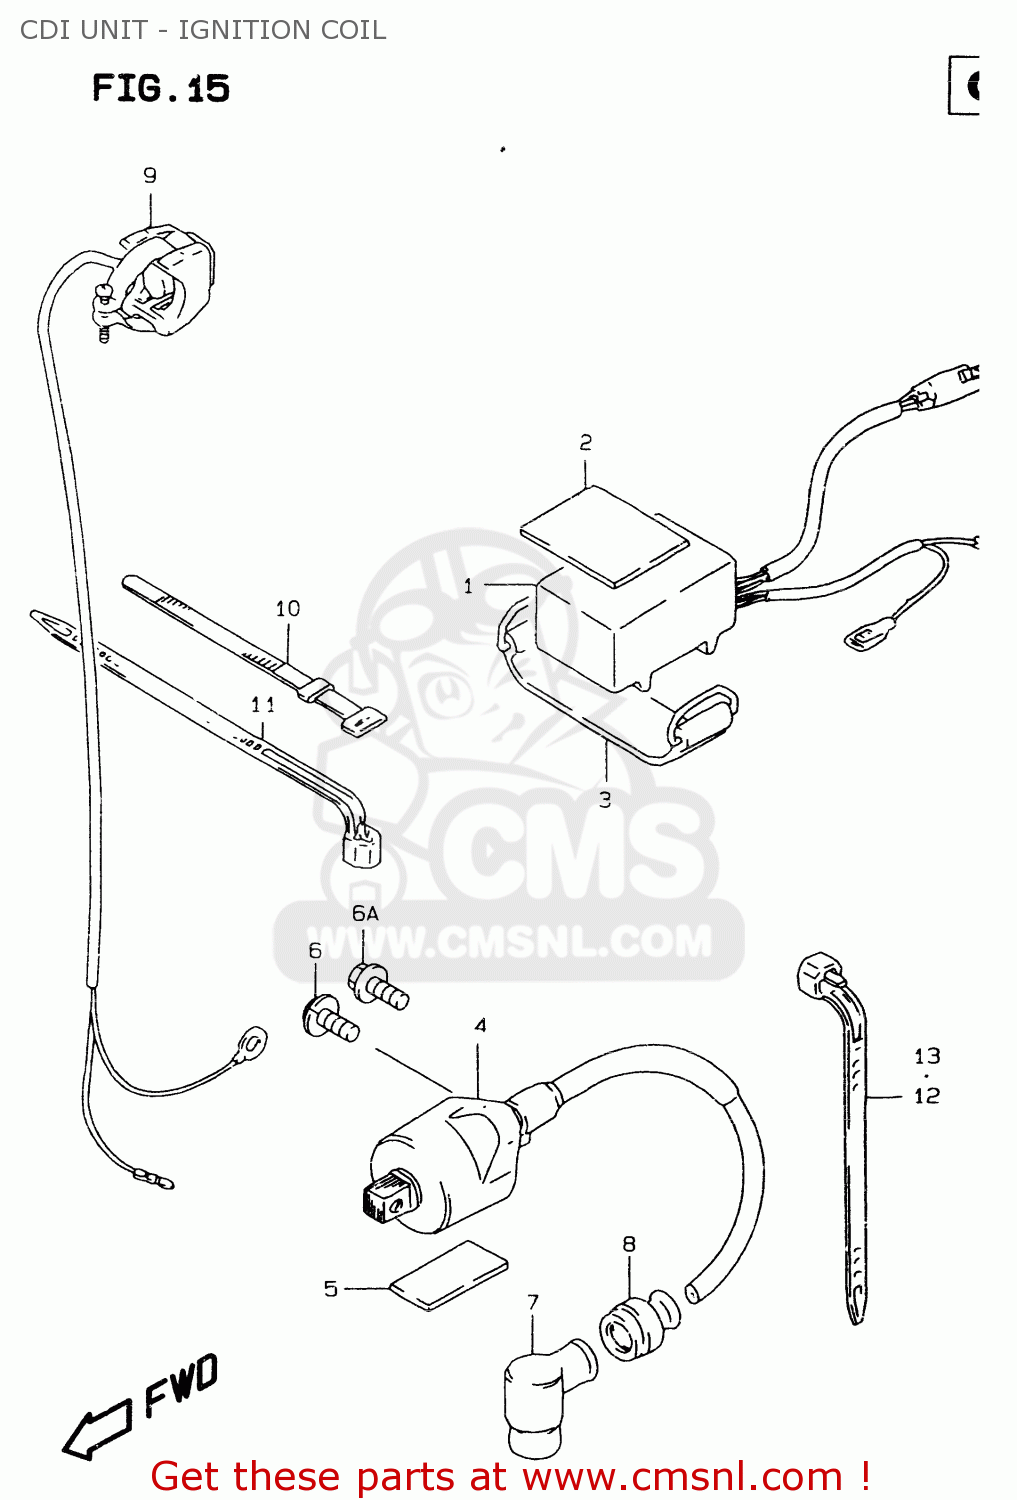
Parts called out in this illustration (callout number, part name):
1	CDI UNIT
2	PROTECTOR(170X95X3.0)
3	BAND
4	COIL ASSY,IGNITION
5	PROTECTOR(170X95X3.0)
6	SCREW(6X21)
6A	SCREW
7	CAP,SPARK PLUG
8	SEAL,HIGH TENSION CORD
9	SWITCH ASSY,ENGINE STOP
10	CLAMP(L:120)
11	CLAMP L:165
12	CLAMP(L:125)
13	CLAMP(L:95)
